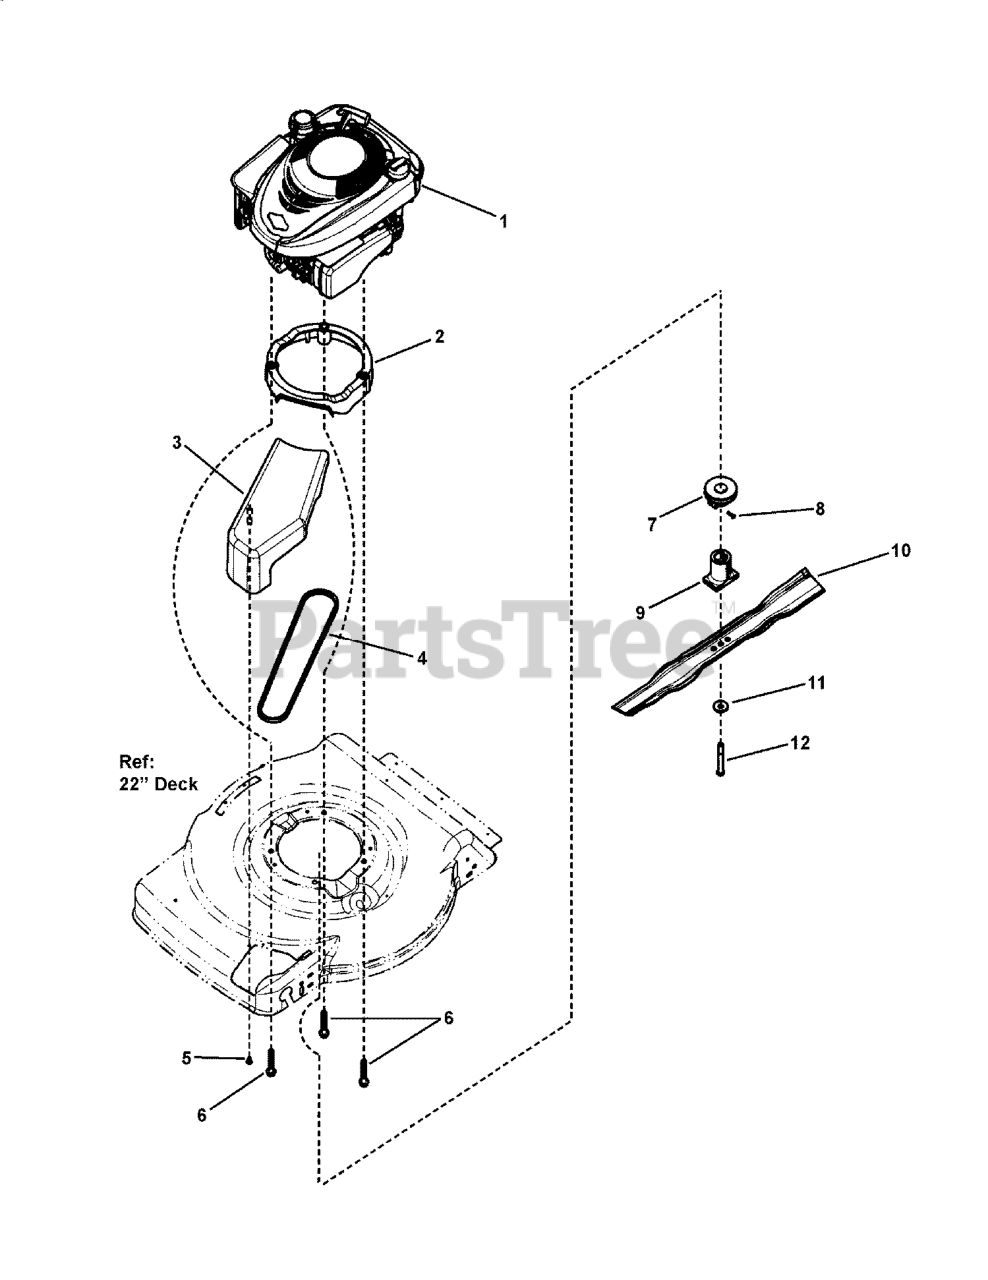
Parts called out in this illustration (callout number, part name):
1	* ENGINE, B&S, 6.75 Series Qtm, Euro
2	ASSY, Engine Spacer, 22 WBM, Propelled
3	COVER, Belt, Plastic
4	BELT, Drive 22 WBM, SS (3L sect. 33.75 effective length)
5	SCREW, Round Washer Hex Head Torx, Hi-Lo
6	BOLT, 3/8-16 x 2-1/2" Hex Washer Face
7	PULLEY, Engine, 22 Deck, Single Speed
8	SCREW, #8-11 x 5/8 Poly
9	HUB, Blade, 22 Deck
10	BLADE, 22 Walk Mower
11	WASHER, Bellville, .38 ID x 1.183 OD
12	BOLT, Hex Head, 3/8-24 x 3-1/4, GR 8
